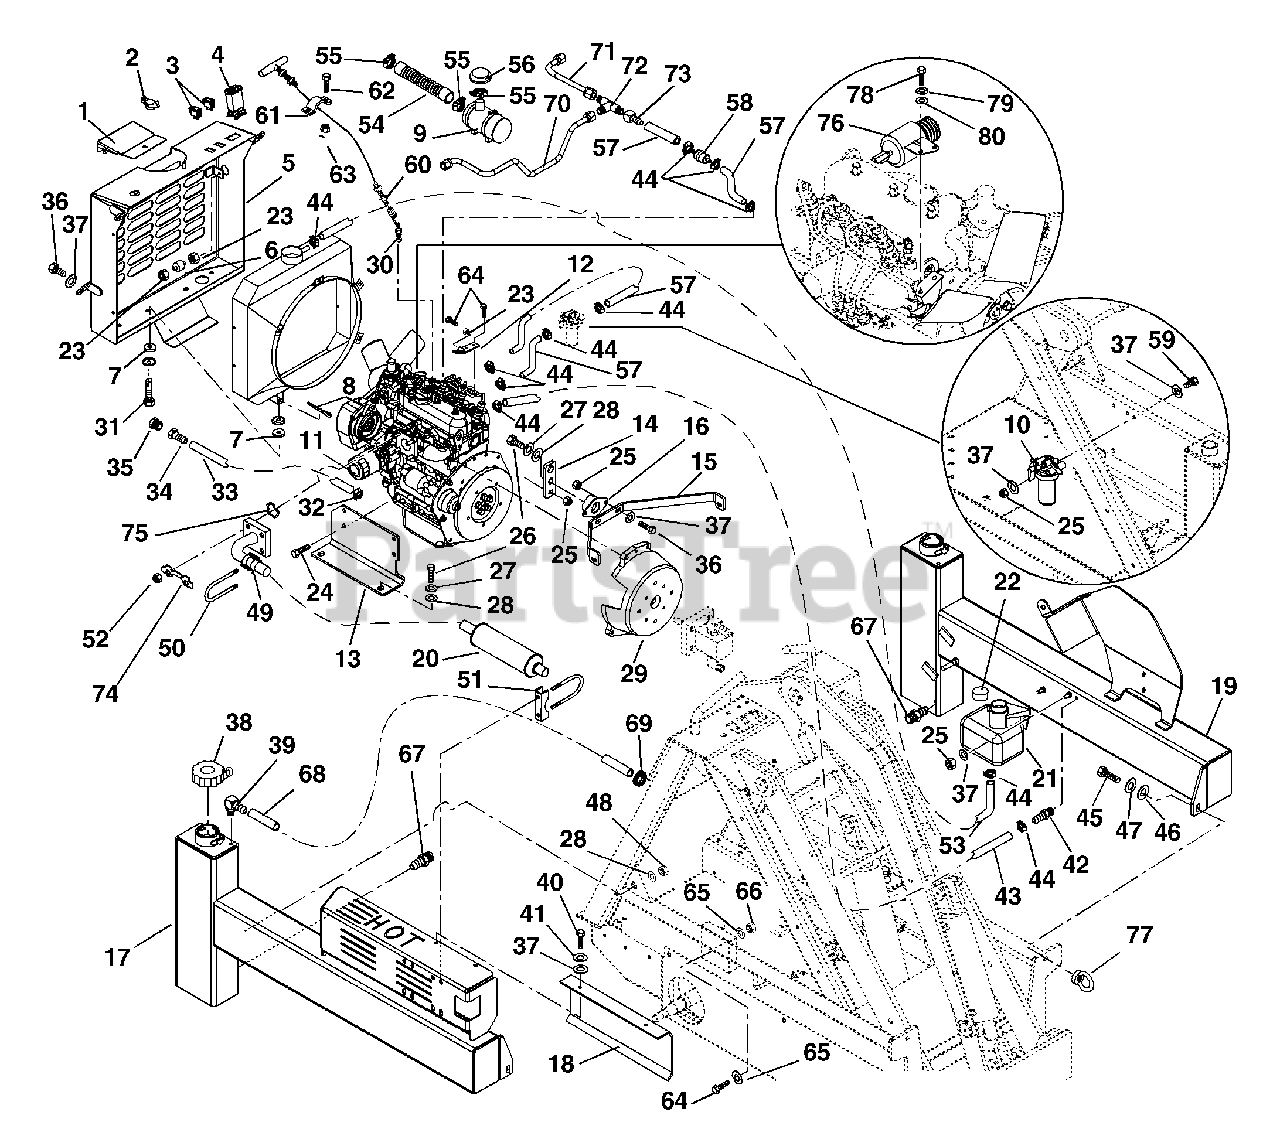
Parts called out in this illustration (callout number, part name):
1	Cover, Radiator Cap
2	Knob, Hand
3	Light Indicator
4	Hour Meter
5	Guard, Radiator
6	Mount, Stud/Plate
7	Isolator
8	Engine, Kubota (D722B-1 (REP))
9	Filter, Air-Diesel
10	Filter, Fuel-Kubota Diesel
11	Filter, Oil-Kubota Diesel
12	Bracket, Throttle Cable
13	Mount, Engine Right Hand Diesel
13	Mount, Engine Left Hand Diesel
14	Plate, Tie
15	Bracket, Upper Engine
16	Mount, Engine
17	Tank, Fuel Diesel Right Hand
18	Bracket, Muffler
19	Tank, Fuel Diesel Left Hand
21	Tank, Plastic 1.5 Quart
22	Cap, 1.62 Vented
23	Nut-Hex M6 x 1.0
24	Bolt, Hex M10-1.25 x 20
25	Nut-Locking-Nylon M8-1.25
26	Bolt-Hex .50-20X1.00 Grade 5
27	Washer-Locking .50 x .125
28	Washer-Flat-Steel .531 x 1.06 x .095
29	Housing, Bell Kubota Assembly
30	Swivel Assembly
31	Bolt,Hex M10-1.25X40 with Lock Hole
32	Clamp-Hose Worm .44/.78 x .53
33	Hose, Oil Drain
34	Adapter, Female Swivel .75-16F
35	Plug, Hose Swivel .75-16M
36	Bolt-Hex M8-1.25 x 20
37	Washer-Flat-Steel .344 x .688 x .065
38	Cap, Fuel Tank
39	Fitting, Barbed 90 Degree Elbow .125-27M x .25 I.D. Hose
40	Bolt-Hex M8 X 1.25 x 16
41	Washer-Locking .31 x .078
42	Fitting, Barbed .125-27M x .250 I.D. Hose
43	Gas Line-Bulk 1/4" I.D.
44	Hose Clamp
45	Bolt M10 x 1.5 x 40
46	Washer-Flat-Steel .406 x .812 x .065
47	Washer-Locking .44 x .109
48	Nut-Locking-Nylon M12-1.75
49	Pipe, Exhaust
50	Clamp, Muffler U-Bolt
51	Clamp, Muffler 3.50
52	Nut-Hex M8-1.25
53	Hose,5/16 I.D.
54	Hose, Flexible
55	Clamp, 2.25 Diameter Hose
56	Filter, Pre Diesel
57	Hose, .312 I.D.
58	Filter, Fuel .312 I.D. Hose
59	Bolt-Hex M8-1.25 x 65
60	Cable, Throttle-Diesel
61	Clamp, Cable
62	Bolt-Hex M5-.8 x 16
63	Nut-Locking-Nylon M5 .8
64	Bolt-Hex M6-1.0 x 25
65	Washer-Flat-Steel .281 x .62 x .065
66	Nut-Locking-Nylon M6-1
67	Adapter, Male Connector .562-19M x .125-27M
68	Gas Line-Bulk .25 I.D.
70	Tube-Fuel Line Long
71	Tube-Fuel Line Short
72	Adapter-Tee .56-18
73	Fitting-Hose .375-M6
74	Bracket, Lock
75	Washer, Wave
76	Solenoid
77	Nut, Eye M10-1.5
78	Bolt-Hex M6-1 x 16
79	Washer-Locking .25 x .062 Regular
80	Washer-Flat-Steel.312 x .734 x .065
